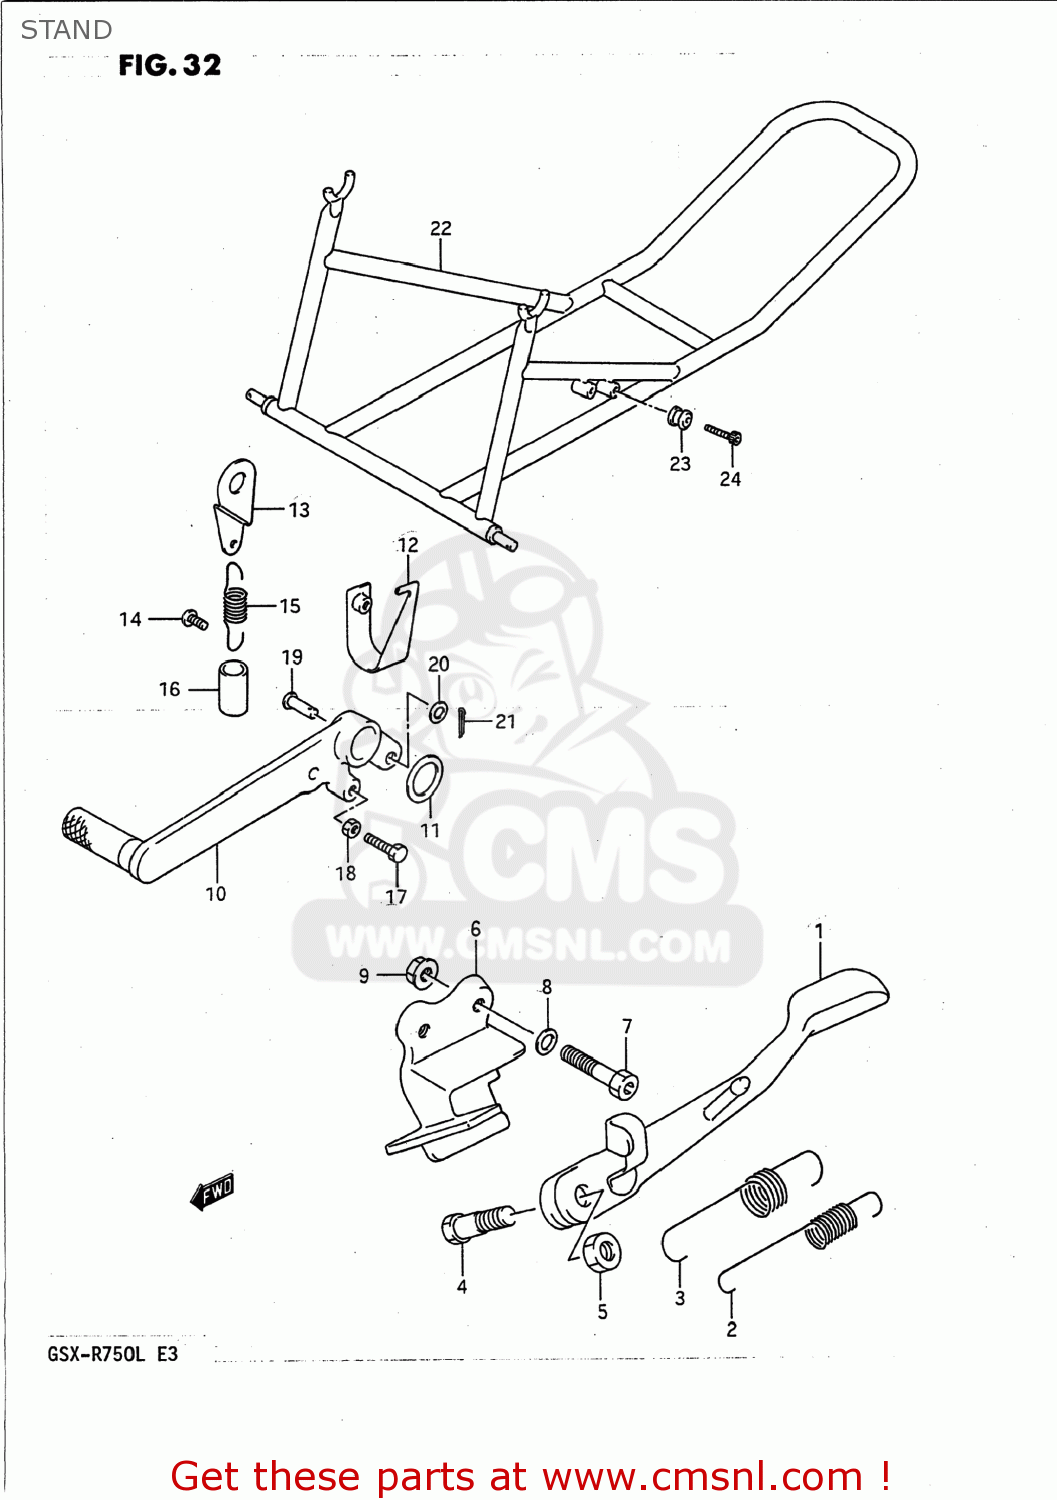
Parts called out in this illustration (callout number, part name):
1	STAND,SIDE
2	SPRING
3	SPRING
4	BOLT(10X38)
5	NUT
6	BRACKET,SIDE STAND
7	BOLT, FRONT RH
8	WASHER
9	NUT
10	PEDAL,BRAKE
11	WASHER(18X24X1)
12	PLATE,BRAKE SPRING,FRONT
13	BRACKET,STOP SWITCH SPRING
14	SCREW(6X12)
15	SPRING
16	TUBE,BRAKE SPRING GUIDE
17	BOLT
18	NUT
19	PIN
20	WASHER
21	PIN
22	STAND ASSEMBLY,REAR
23	HOLDER,STAND
24	BOLT, REAR (8X30)
